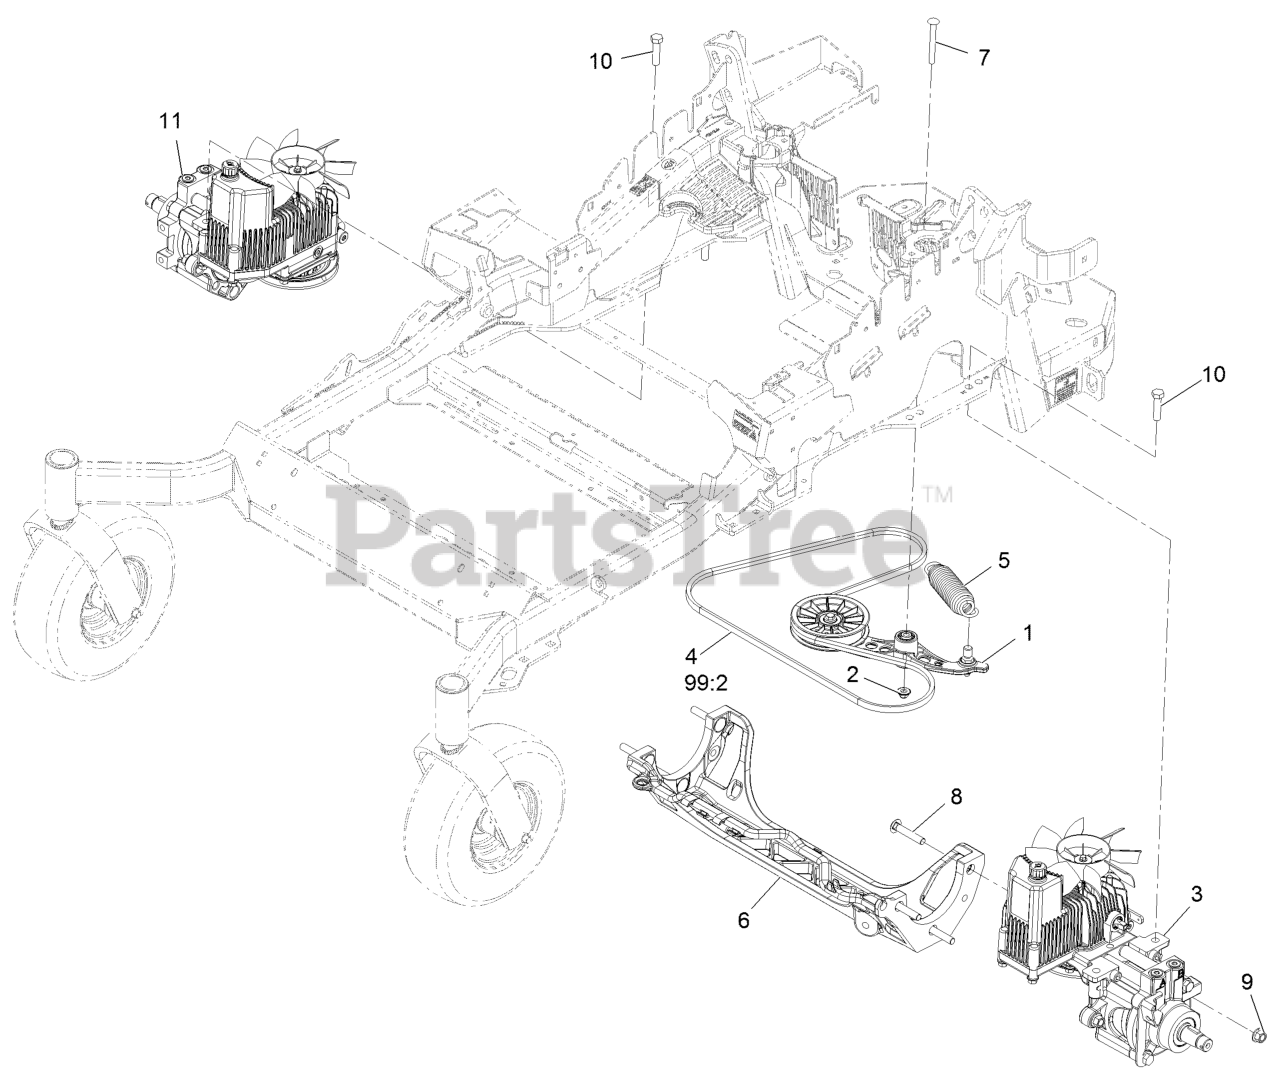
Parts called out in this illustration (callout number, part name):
1	PUMP IDLER ASM
2	Nut-Nyloc 3/8-16 Flg
4	BELT
5	SPRING-EXTENSION
7	BOLT-SHOULDER, CARRIAGE 3/8-16 X 3 1/2
8	SCREW-CARR
9	Nut-Lock 1/2-13
10	SCREW-HH
99	BOTTLE-OIL, 32OZ HYDRAULIC
99:2	BELT
